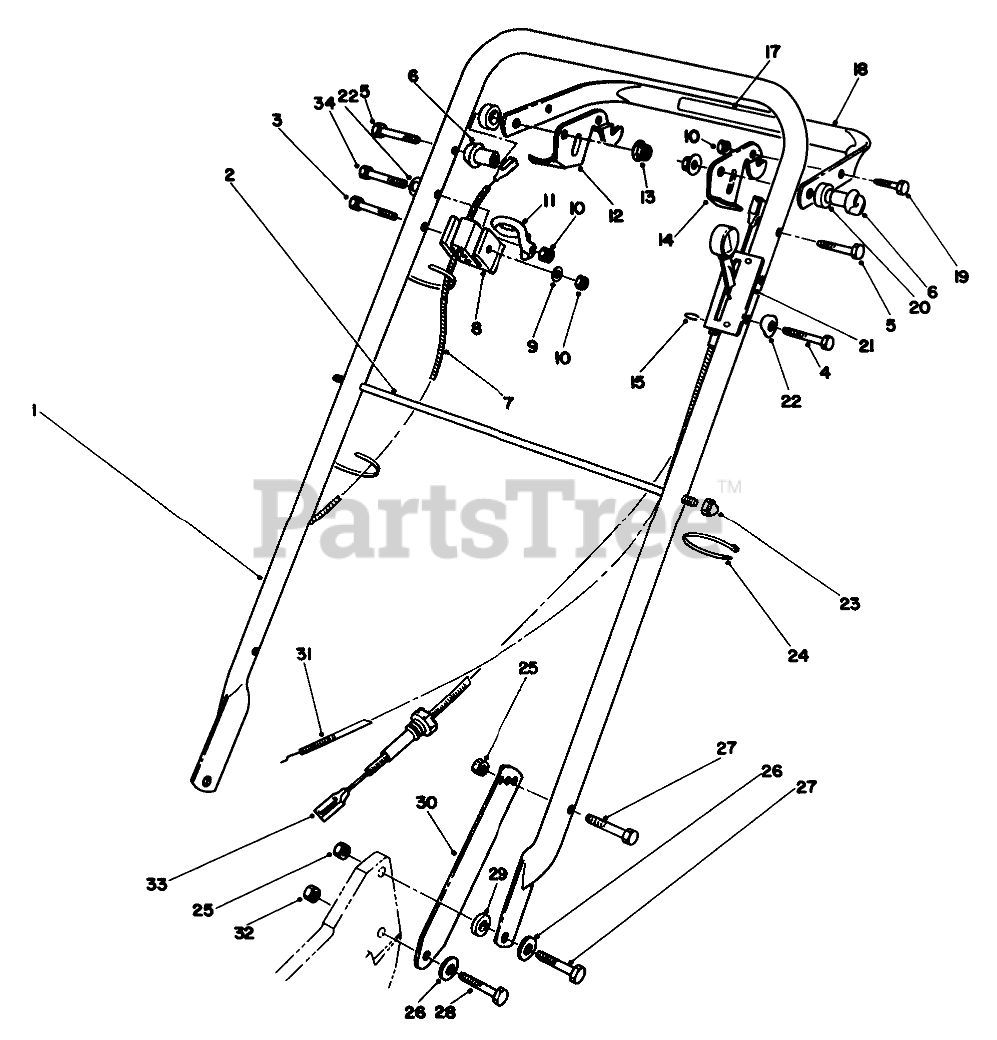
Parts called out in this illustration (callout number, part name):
1	Handle
2	ROD-SUPPORT, BAG
3	SCREW-HH
4	SCREW-HH
5	SCREW-HH
6	SPACER-SUPPORT
7	Cable-Brake
8	SUPPORT-CABLE
9	WASHER-FLAT
10	NUT-LOCK, NI
11	GUIDE-ROPE
12	LEVER-CONTROL
13	NUT-LOCK, NI
14	LEVER-CONTROL
15	E-RING
17	DECAL/TRACTION CONTROL
18	Bar-Control
19	SCREW-HH
20	SPACER-NYLON
21	CONTROL-THROTTLE
22	WASHER
23	NUT-CAP
24	TIE-CABLE
25	NUT-LOCK, NI
26	WASHER-BELLEVILLE
27	SCREW-HH
28	SCREW-HH
29	SPACER-PIN, MOUNTING
30	HANDLE LATCH
31	CABLE-THROTTLE
32	NUT-LOCK, NI
33	CABLE-TRACTION
34	SCREW-HH
